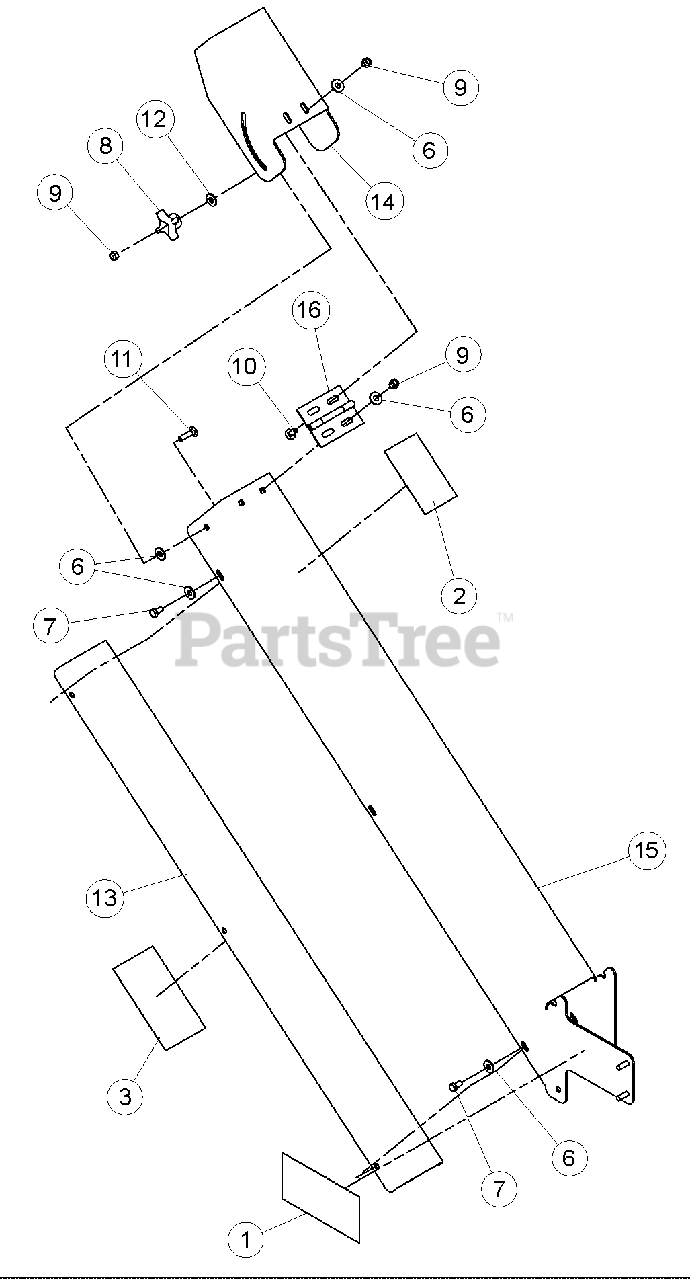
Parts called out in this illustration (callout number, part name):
1	DECAL, KNIFE ACCESS
2	DECAL, DISCHARGE
3	DECAL, INLET AND DISCHARGE
6	WASHER, 5/16" FLAT
7	BOLT, 5/16 X 5/8" HEX HD
8	KNOB, 5/16" SPOUT
9	NUT, 5/16" NYLOCK
10	BOLT, 5/16 X 3/4" CRG
11	BOLT, 5/16 X 1-1/4" CRG
12	WASHER, 5/16" NYLON
13	WELDMENT, TOP DISCHARGE CHUTE
14	CAP, DISCHARGE
15	WELDMENT, CHIPPER DISCHARGE
16	HINGE, DISCHARGE CAP
